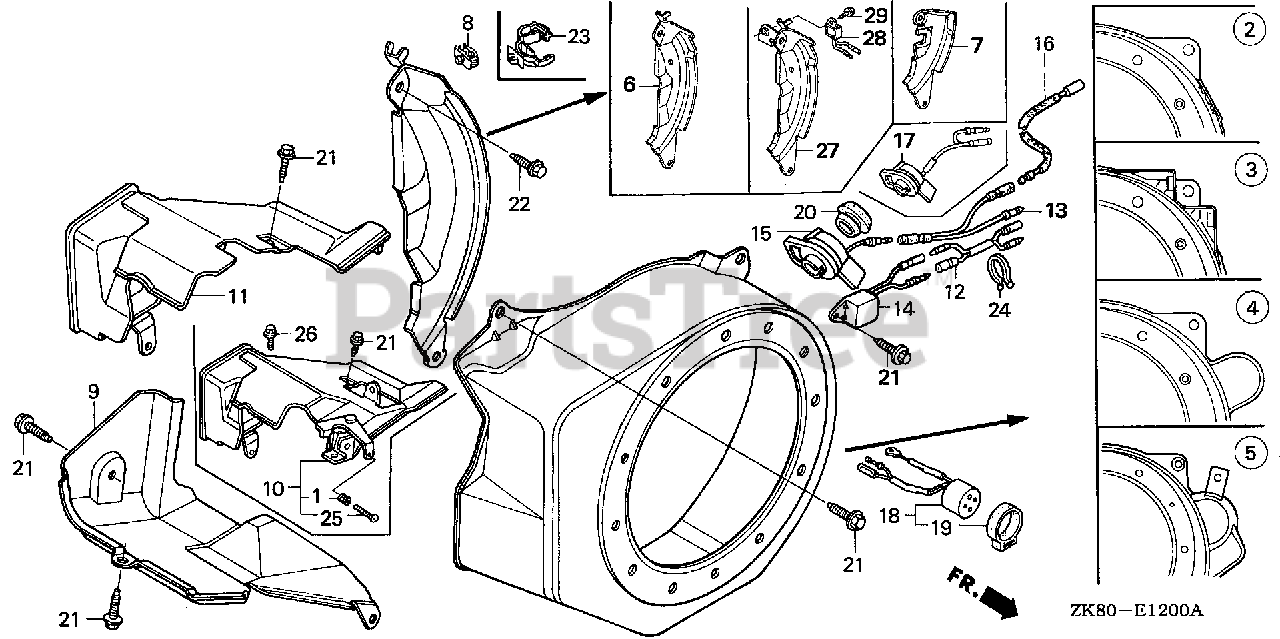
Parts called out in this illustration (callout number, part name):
2	COVER, FAN *R280* (POWER RED)
15	SWITCH ASSY., ENGINE STOP
21	BOLT, FLANGE (6X12) (CT200)
22	BOLT, FLANGE (6X20) (CT200)
23	CLIP, HARNESS
27	PLATE, SIDE (OIL ALERT)
28	ALERT UNIT, OIL
29	BOLT, FLANGE (6X8)
